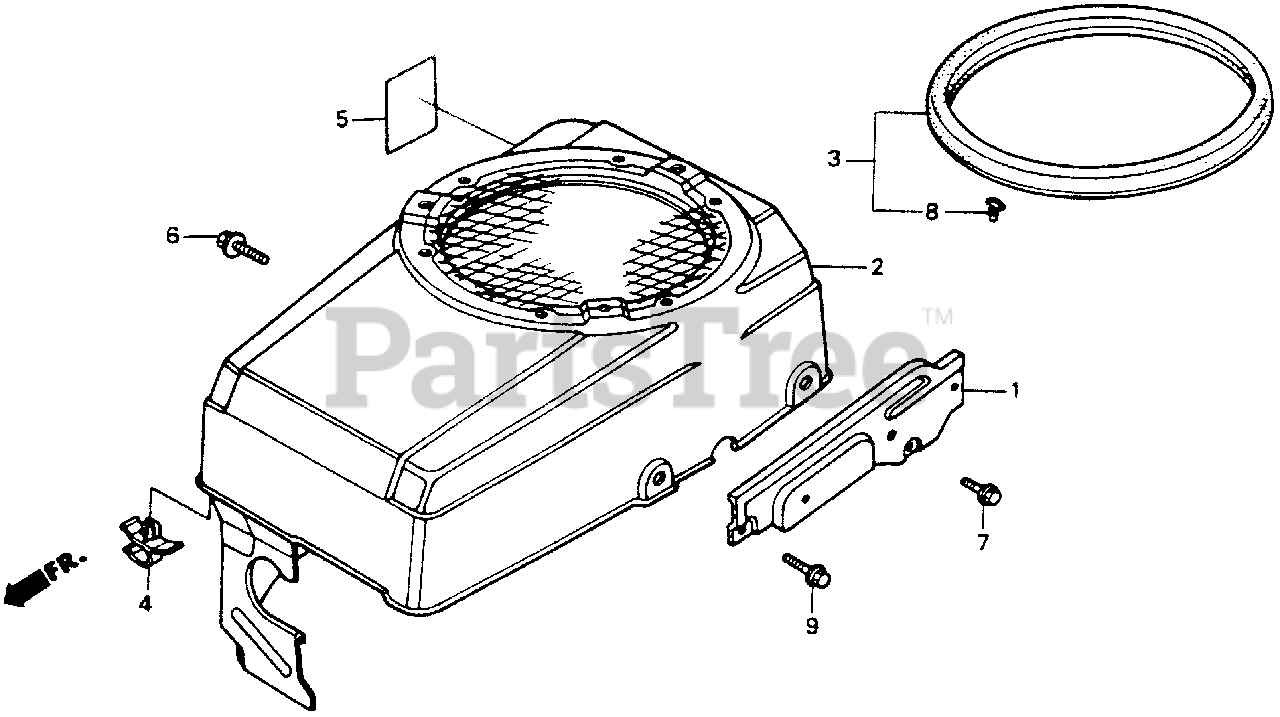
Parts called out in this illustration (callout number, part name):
1	STAY, TANK (NOT AVAILABLE)
2	COVER, FAN
3	SEAL, LAWN COVER
4	CLIP, WIRE HARNESS
5	MARK, OIL CAUTION
6	BOLT, FLANGE (6X12) (CT200)
7	BOLT, FLANGE (6X16)
8	CLIP, CANOE
9	BOLT, FLANGE (8X22)
